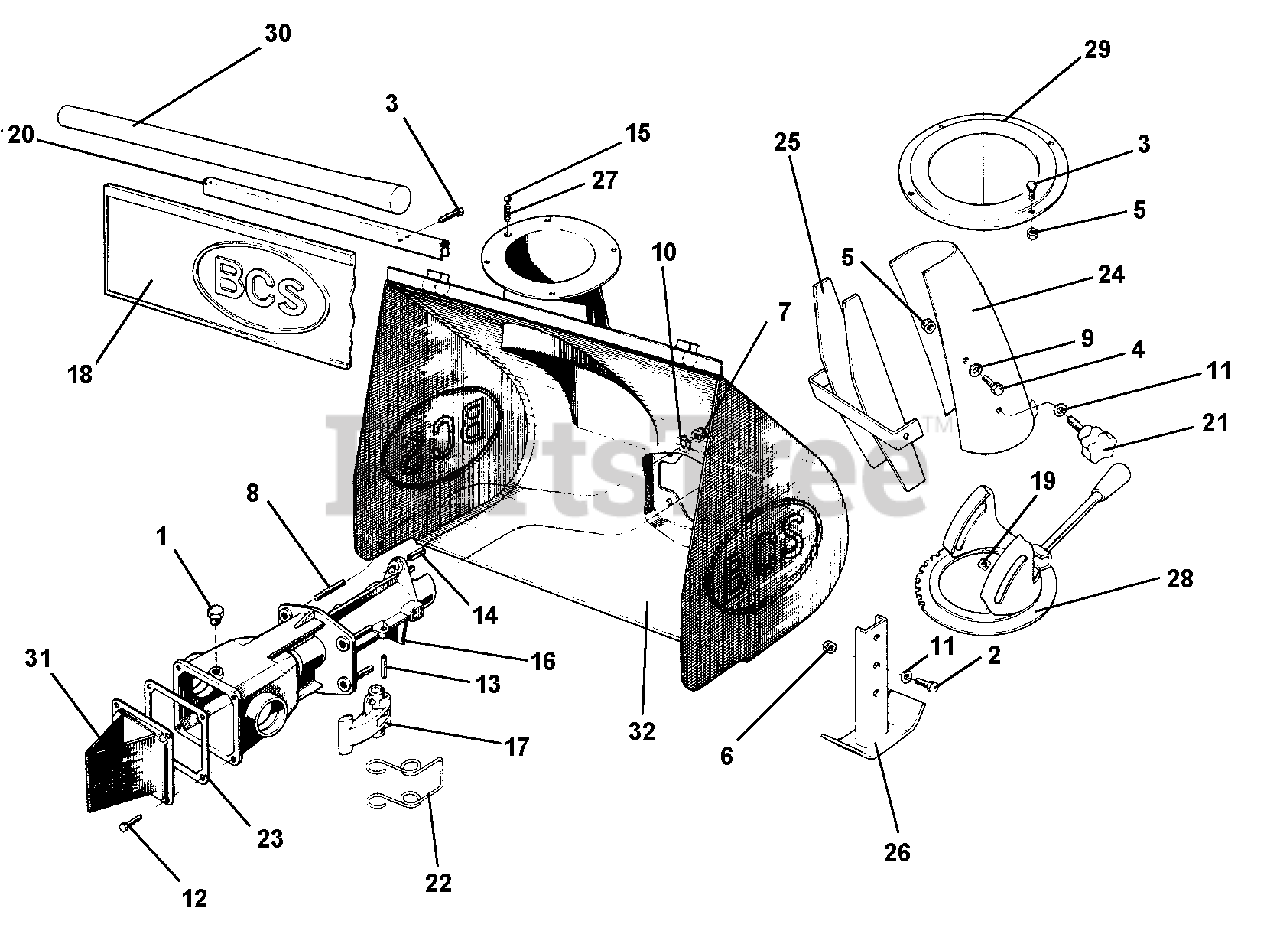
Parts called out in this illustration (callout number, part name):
1	PLUG 1/4 GAS
2	SCREW M8 X 16
3	SCREW M6 X 12
4	SCREW TE M6 X 16
7	NUT, SELF LOCKING M8
8	STUD M8 X 32 X 14 X 14
9	WASHER, FLAT 6.4
10	WASHER, FLAT 8.4
11	FLAT WASHER 10.5 X 21
12	SCREW M6 X 12
13	SPIRAL PIN 12 X 26
14	LOCKING PIN 12 X 26
15	BALL 11/32 RIV RB 8.73
19	SQUARE NUT M10
20	SNOW FLAP HOLDER
21	KNOB WITH SCREW
25	FUNNEL GRATE
28	FUNNEL FLANGE
29	FLANGE FOR RING
